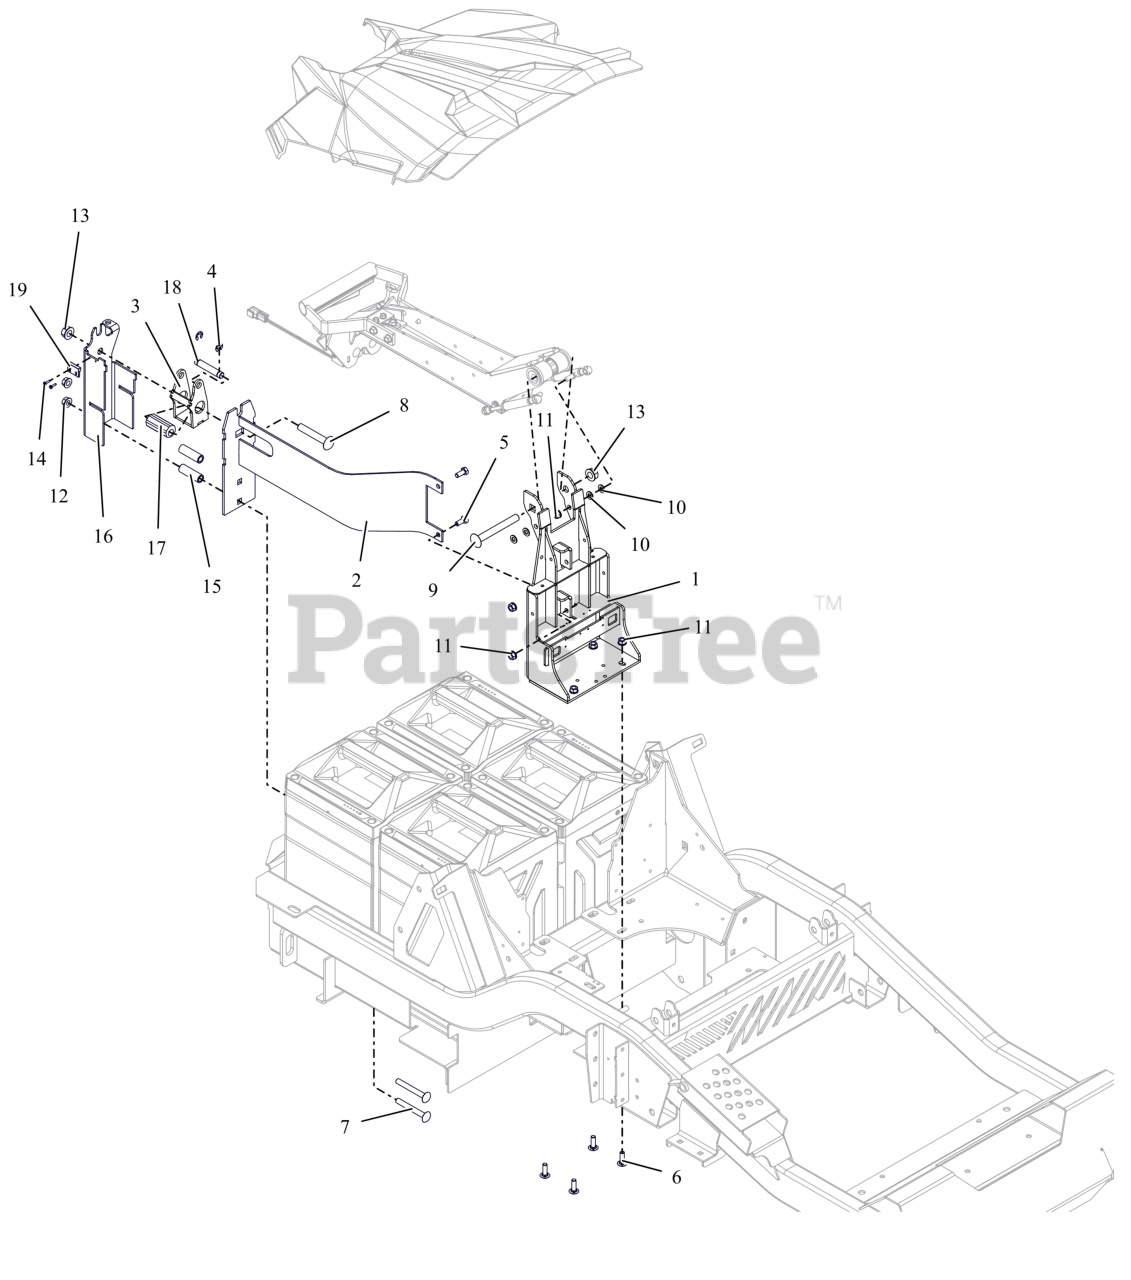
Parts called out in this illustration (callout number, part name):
1	WLDMT, BATTERY HOLDDOWN PIVOT (RED)
2	WLDMT, ECCENTRIC MTG (RED)
3	WLDMT, ECCENTRIC
4	RG-RTNG-EXT .438X.035
5	BLT,HEX .31-18X.75 G5 ZCC
6	BLT,RHSSN .31-18X1.00 G5 ZCC
7	BTL,RHSSN .375-16 X 3 G5 ZCC
8	BTL,RHSSN .500-13 X 3 G5 ZCC
9	BTL,RHSSN .500-13X 4.0 G5 ZCC
10	WSHR,FLT .323X.625X.062 ZCC
11	NUT,LK-CTR-FLG .31-18 GF ZCC
12	NUT-LK-CTR-FLG .375-16 GF ZCC
13	NUT-LK-CTR-FLG .500-13 GG ZCC
14	SCR-TAP #4-40X.50 HWH ZCC
15	SPCR, LATCH BRKT (BLACK)
16	BRKT, ECCENTRIC MTG (RED)
17	ECCENTRIC, HOOD LATCH
18	ROD, LATCHING
19	SWITCH, MAGNET (NO WIRE)
